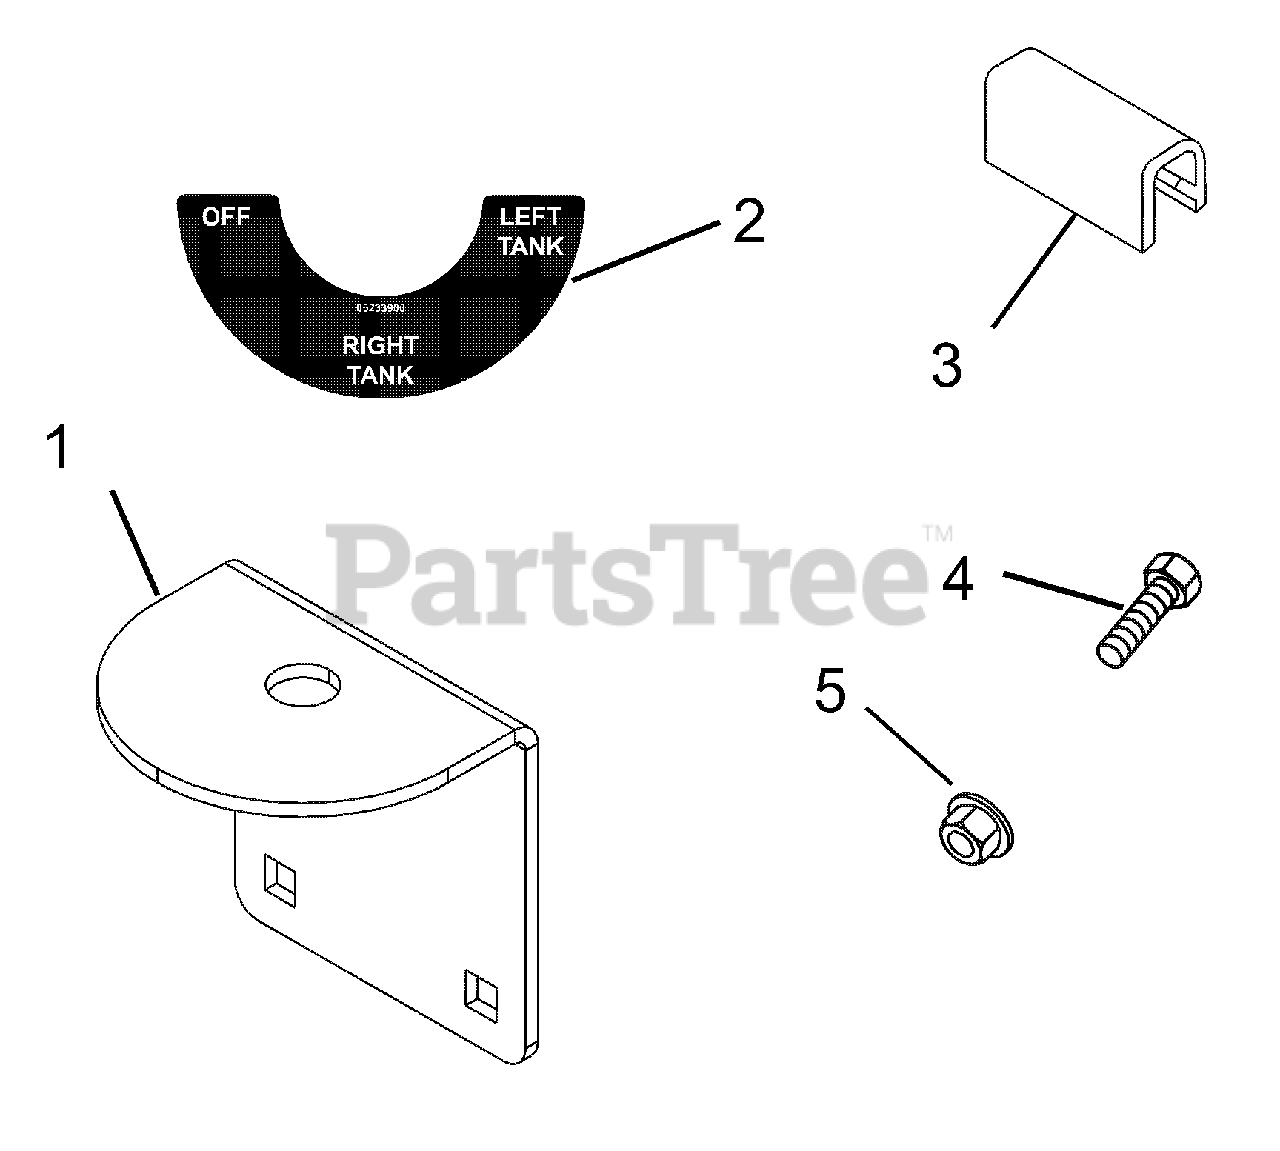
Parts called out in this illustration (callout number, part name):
1	BRKT, FUEL VALVE MNTG
2	DECAL, FUEL VALVE
3	STRIP, COWL
4	@BLT-HEX .31-18X.75 GR5 YWZC
5	DECAL, FUEL VALVE
